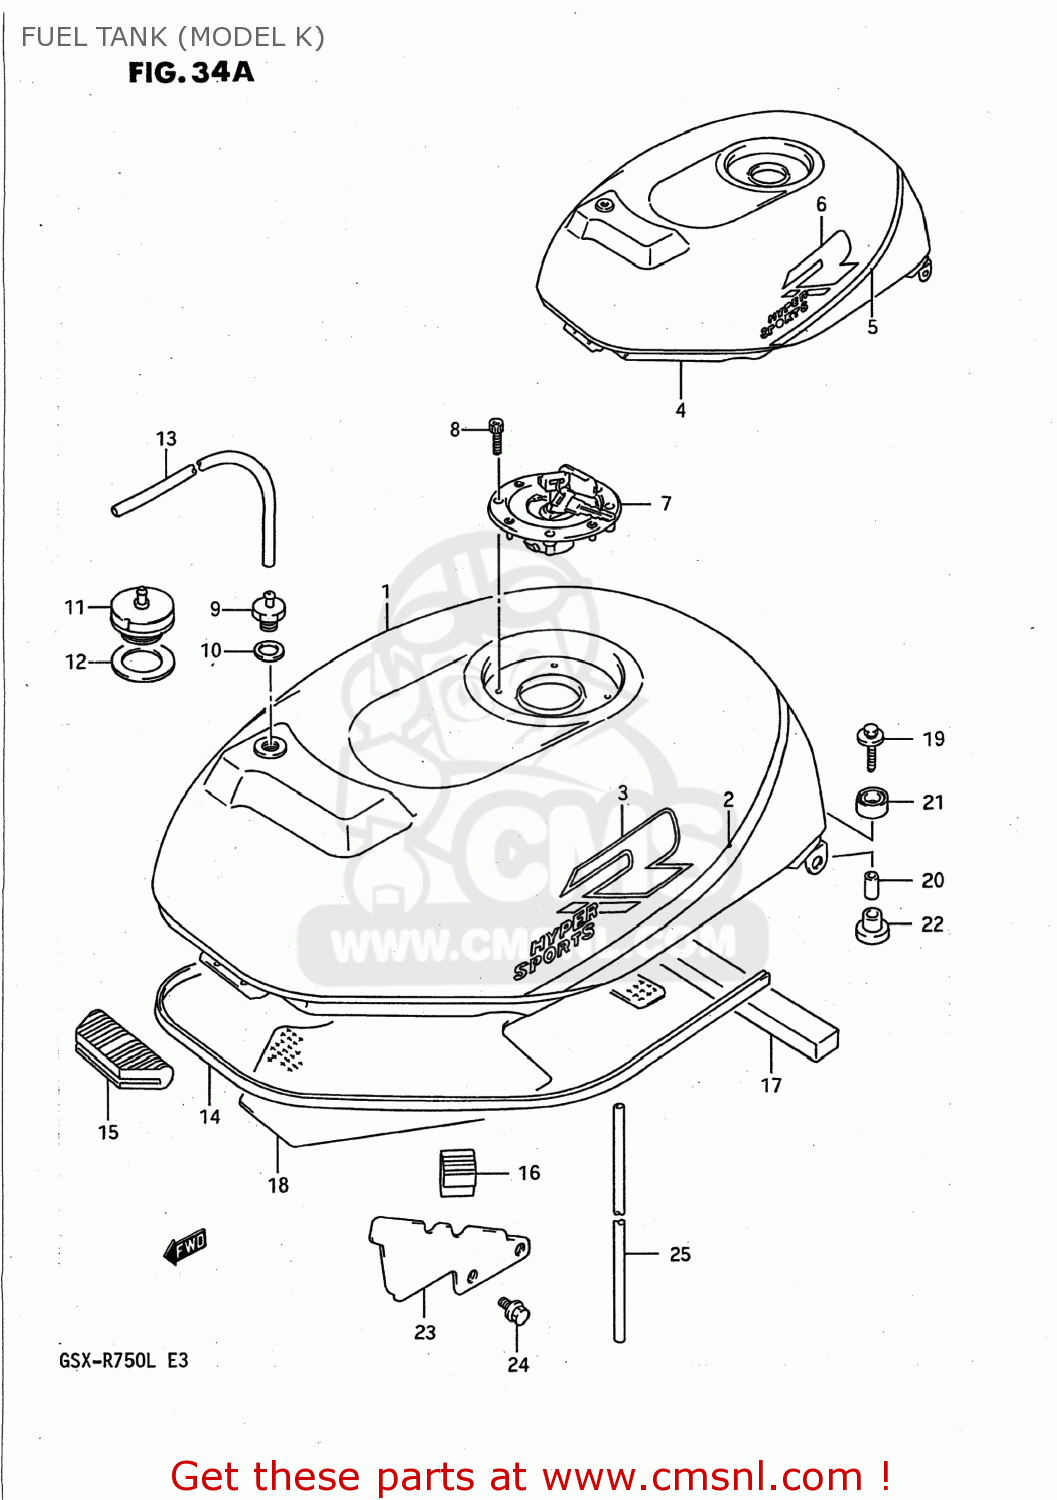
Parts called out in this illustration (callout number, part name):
1	TANK ASSEMBLY,FUEL
2	TAPE,FUEL TANK STRIPE
3	EMBLEM,FUEL TANK
4	TANK ASSEMBLY,FUEL
5	TAPE,FUEL TANK STRIPE
6	EMBLEM,FUEL TANK
7	CAP SET,FUEL TANK
8	BOLT(5X20)
9	PLUG,FUEL TANK BREATHER
10	GASKET(12.5X20X2.5) (NAS)
11	(CA) VALVE,FUEL TANK BREATHER
12	GASKET 27X40X2.5 (NAS)
13	HOSE
14	MOLDING,FUEL TANK
15	CUSHION,FUEL TANK FR
16	CUSHION,TANK,S
17	CUSHION, AIR SEAL
18	HEAT SHIELD,FUEL TANK
19	BOLT(6X35)
20	SPACER
21	CUSHION
22	CUSHION
23	COVER,FRONT,LEFT
24	BOLT
25	HOSE
